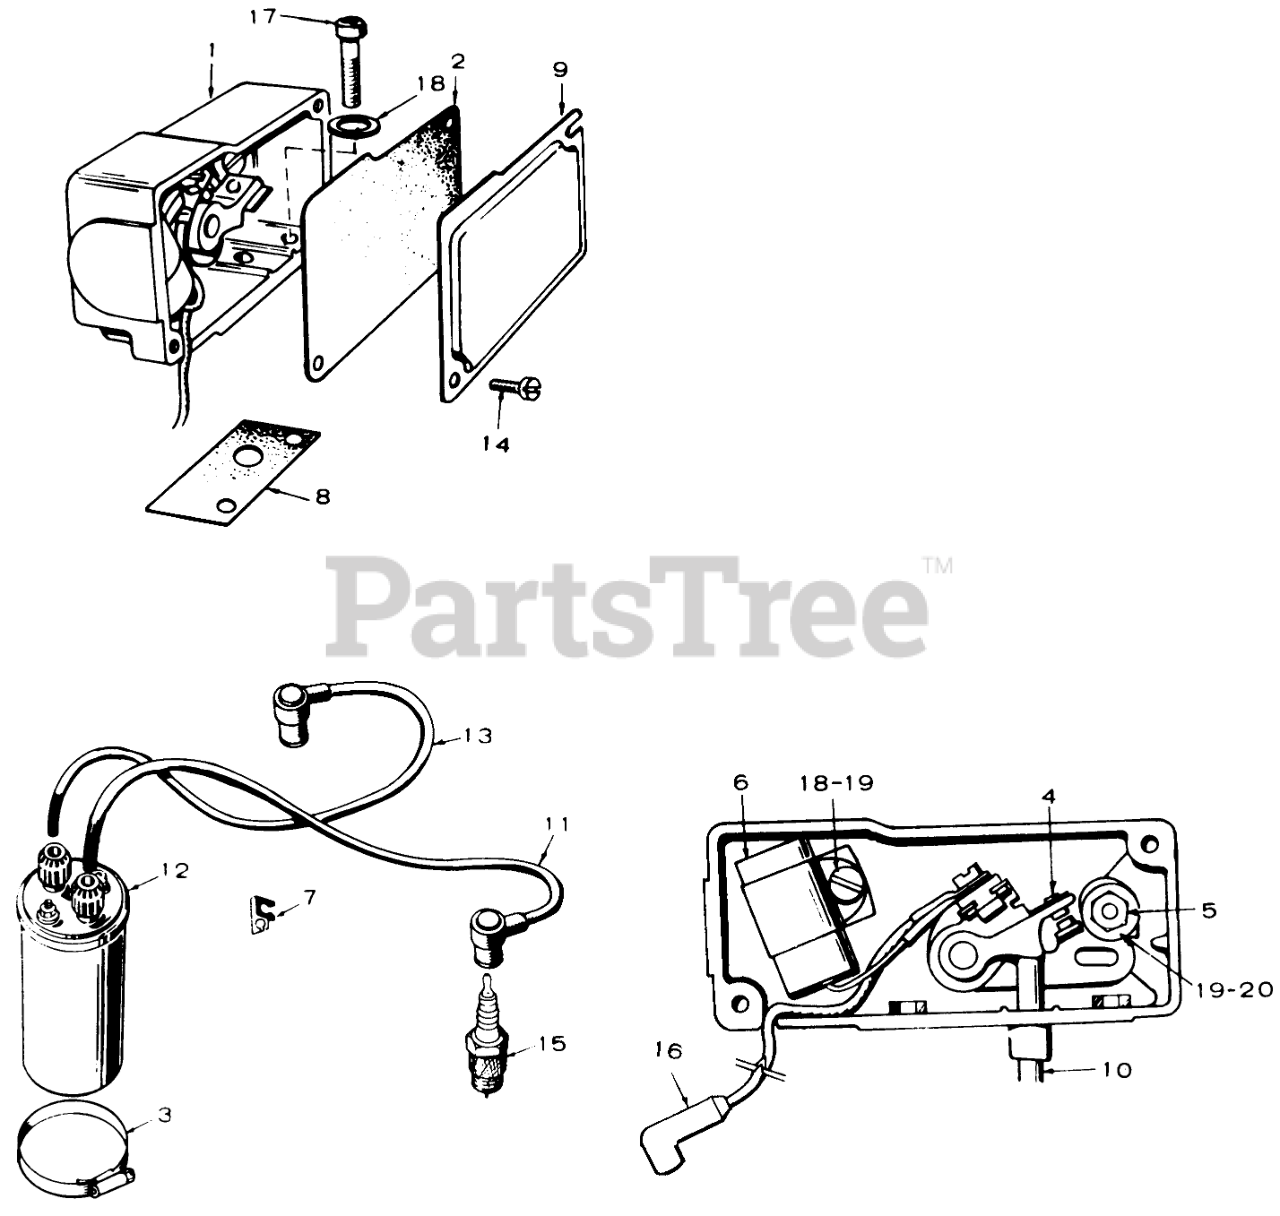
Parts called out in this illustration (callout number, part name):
1	Box Assembly, Breaker (Includes Parts Marked )
2	Gasket-Breaker Box Cover
3	Coil Mounting Clamp
4	SET-BREAKER POINT
6	CONDENSER-BRKER PTS
7	Clip,Spark Plug Cable
8	Gasket,Breaker Box Mounting
9	Breaker Box Cover
10	Plunger
11	Cable, Spark Plug (19")
12	Ignition Coil
13	Spark Plug Cable 16 3/4 in
14	Pan HD Screw 8-32 X 5/16
15	Spark Plug
16	Wire Assy-Points To Coil
17	Hex Bolt 1/4-20 X 3/4 in
18	WASHER, LOCK
18	Breaker Box Mounting (1/4")
18	Condenser Mounting (#8)
19	SCREW, PAN HEAD
19	Pan HD Screw-Condenser
19	Pan HD Screw-Breaker Points
20	Nut-Breaker Points
